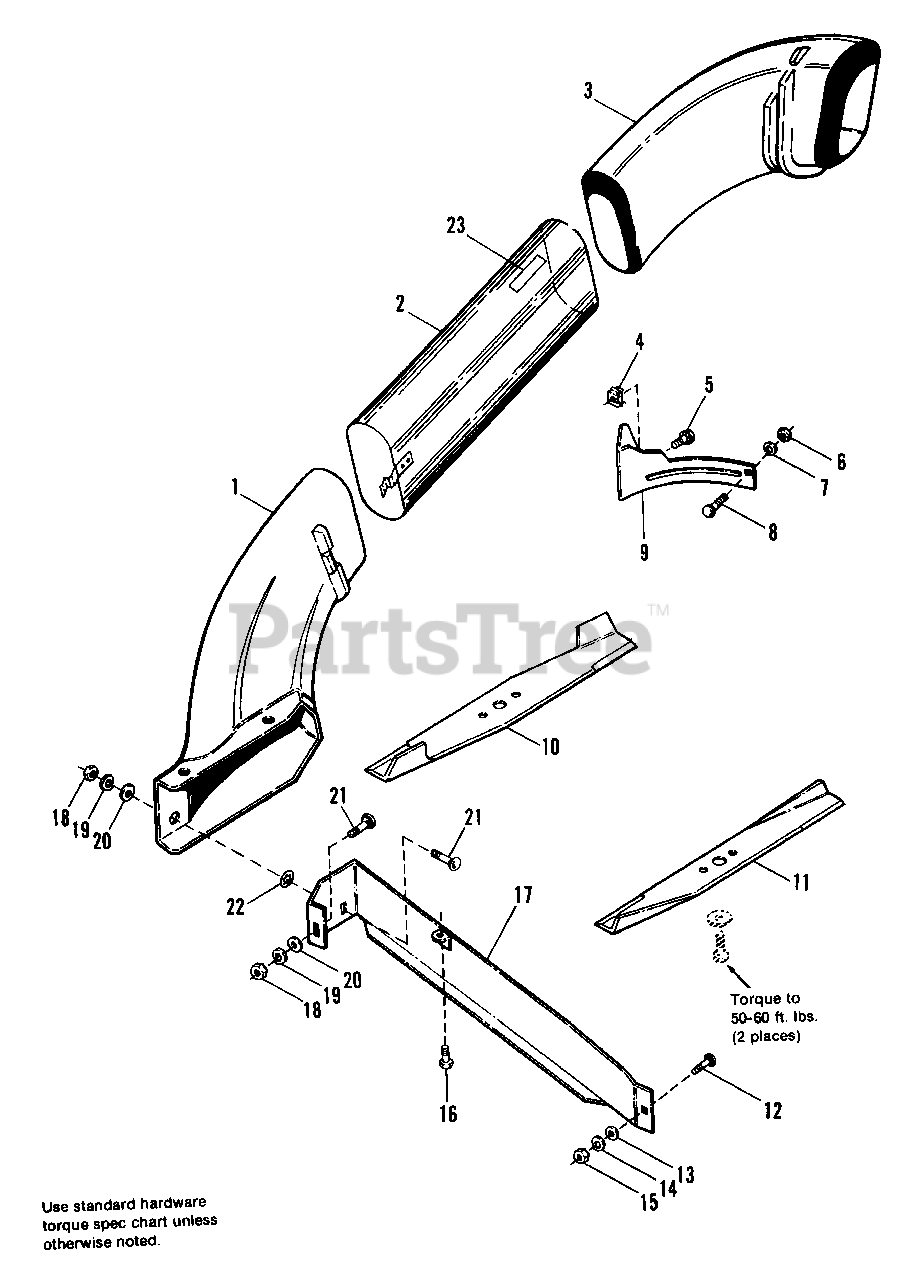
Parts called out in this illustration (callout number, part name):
4	NUT, Retainer, 1/4-20
5	SCREW, Whizlock, 1/4-20 x 1/2
6	NUT, Hex, 1/4-20
7	LOCKWASHER, 1/4
8	BOLT, Carriage, 1/4-20 x 5/8
9	BAFFLE, Deflector Side
10	BLADE, R.H.
11	BLADE, L.H.
12	BOLT, Carriage, 5/16- 18 x 7/8
13	WASHER, 1/4
14	LOCKWASHER, 5/16
15	NUT, Hex, 5/16-18
16	SCREW, Taptite, 5/16-18 x 1/2
17	BAFFLE ASSY., Discharge
18	NUT, Hex, 3/8-16
19	LOCKWASHER, 3/8
20	WASHER, 3/8
21	BOLT, Carriage, 3/8-16 x 3/4
22	NUT, Push-On
23	DECAL, Cleaning Instructions
